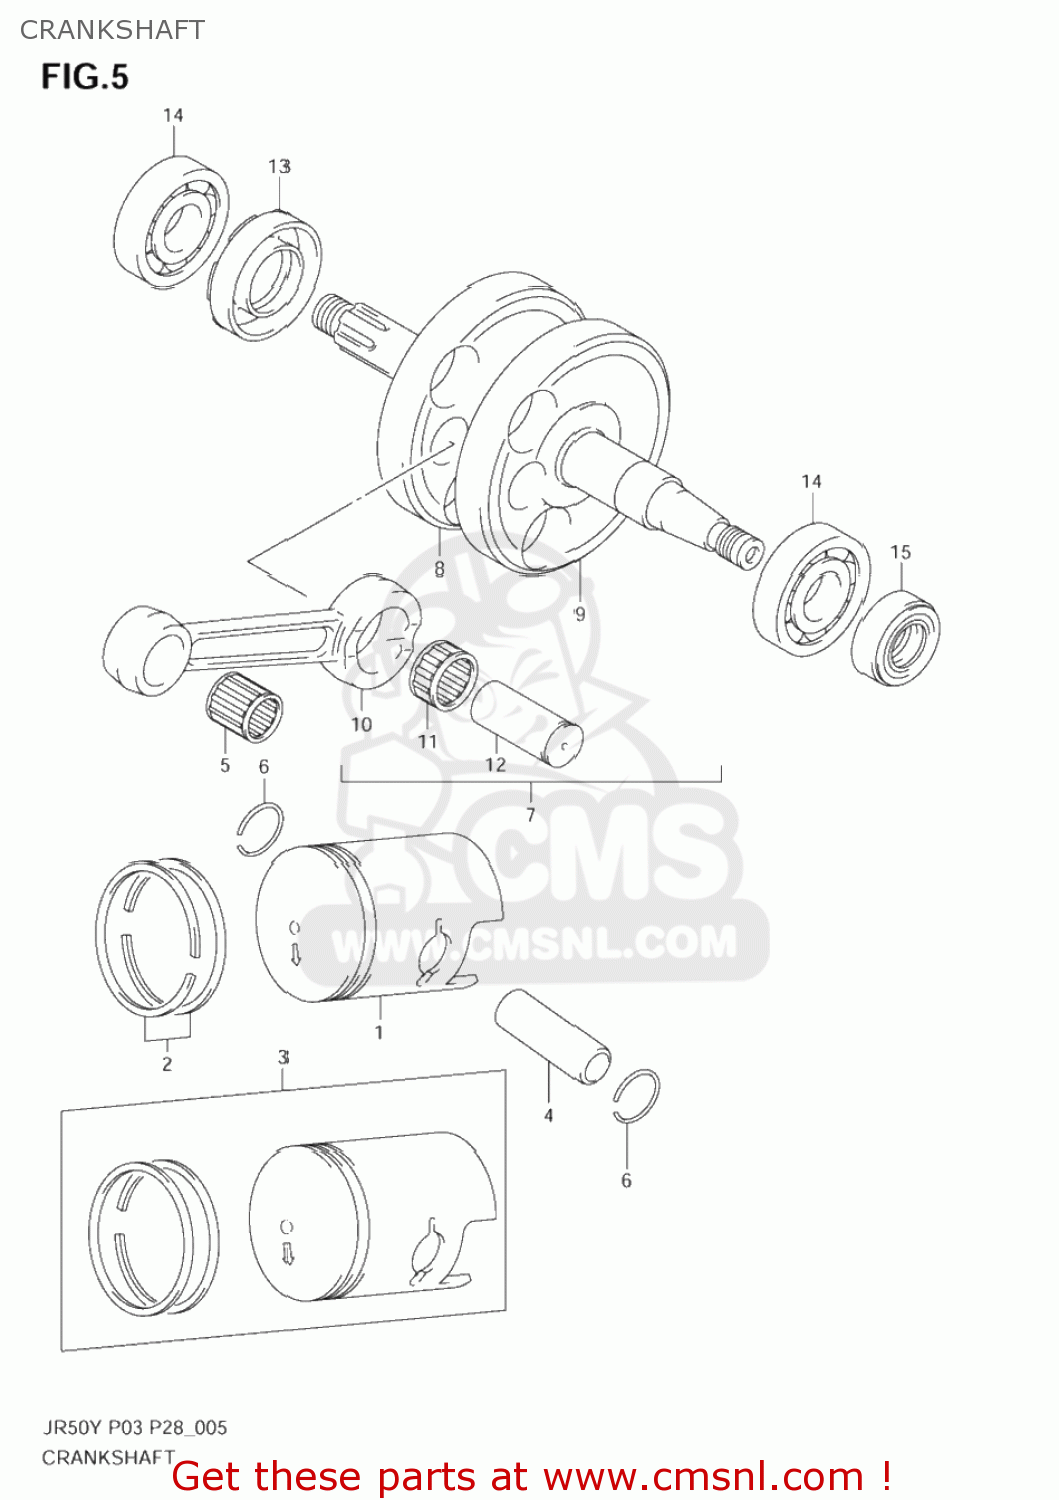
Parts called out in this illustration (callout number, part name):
1	PISTON
2	RING SET,PISTON
3	PISTON SET(OS:0.5)
4	PIN,PISTON
5	BEARING(12X16X16)
6	RING,SNAP
7	CRANKSHAFT ASSY
8	CRANKSHAFT,R
9	CRANKSHAFT,L
10	ROD,CONNECTING
11	BEARING(15X21X9.8)
12	PIN,CRANK
13	SEAL,OIL(22X40X8)
14	BEARING(17X40X12)
15	OIL SEAL (17X29X7)
